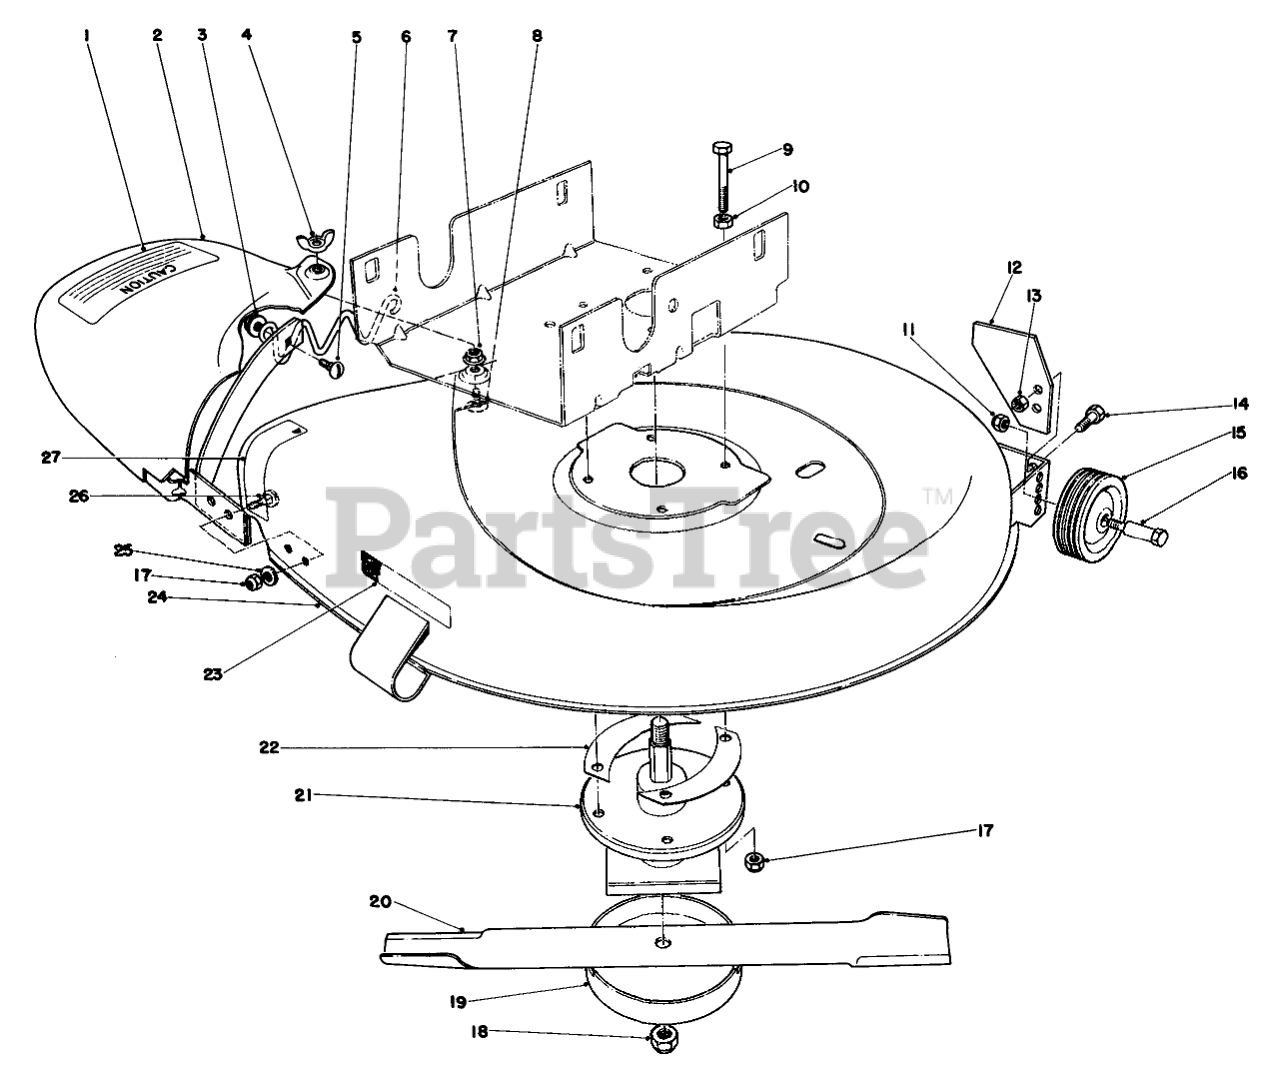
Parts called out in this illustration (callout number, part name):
1	Decal
2	DEFLECTOR WA R
3	NUT-LOCK, HHF
4	Wing Nut
5	SCREW-CARRIAGE
6	FOOT GUARD BRKT
7	PAL NUT
8	Carriage Bolt
9	SCREW-HH
10	NUT-JAM
11	Nut
12	Deck Stop
13	NUT-LOCK, CONE
14	SCREW-HH
15	Wheel
17	NUT-LOCK, CONE
19	Cup
20	Blade
21	Mower Spindle
22	Shim-Deck Spindle
23	Decal-Deck Inst.
24	HOUSING WA R
25	WASHER-FLAT
26	BOLT-CARR
27	Decal Housing
